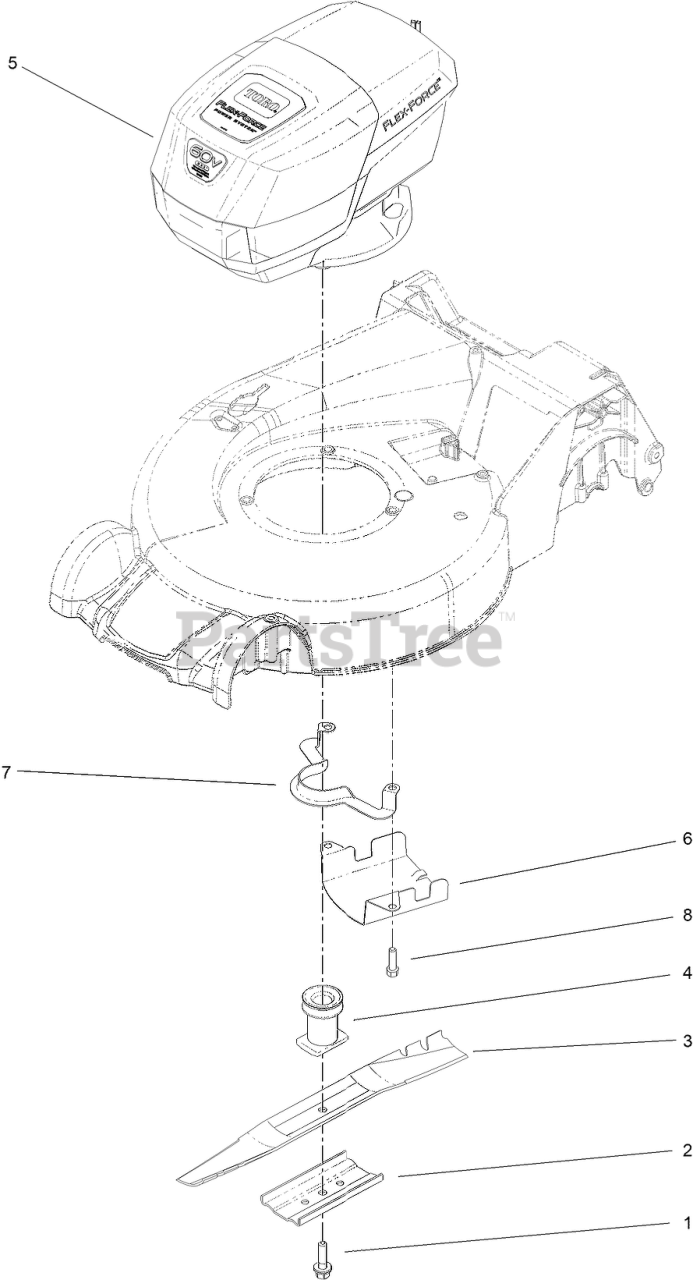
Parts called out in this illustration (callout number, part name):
1	BOLT-BLADE
2	SUPPORT-BLADE
4	DRIVER-BLADE
5	MOTOR MODULE
6	SHIELD-GRASS
7	GUIDE-BELT
